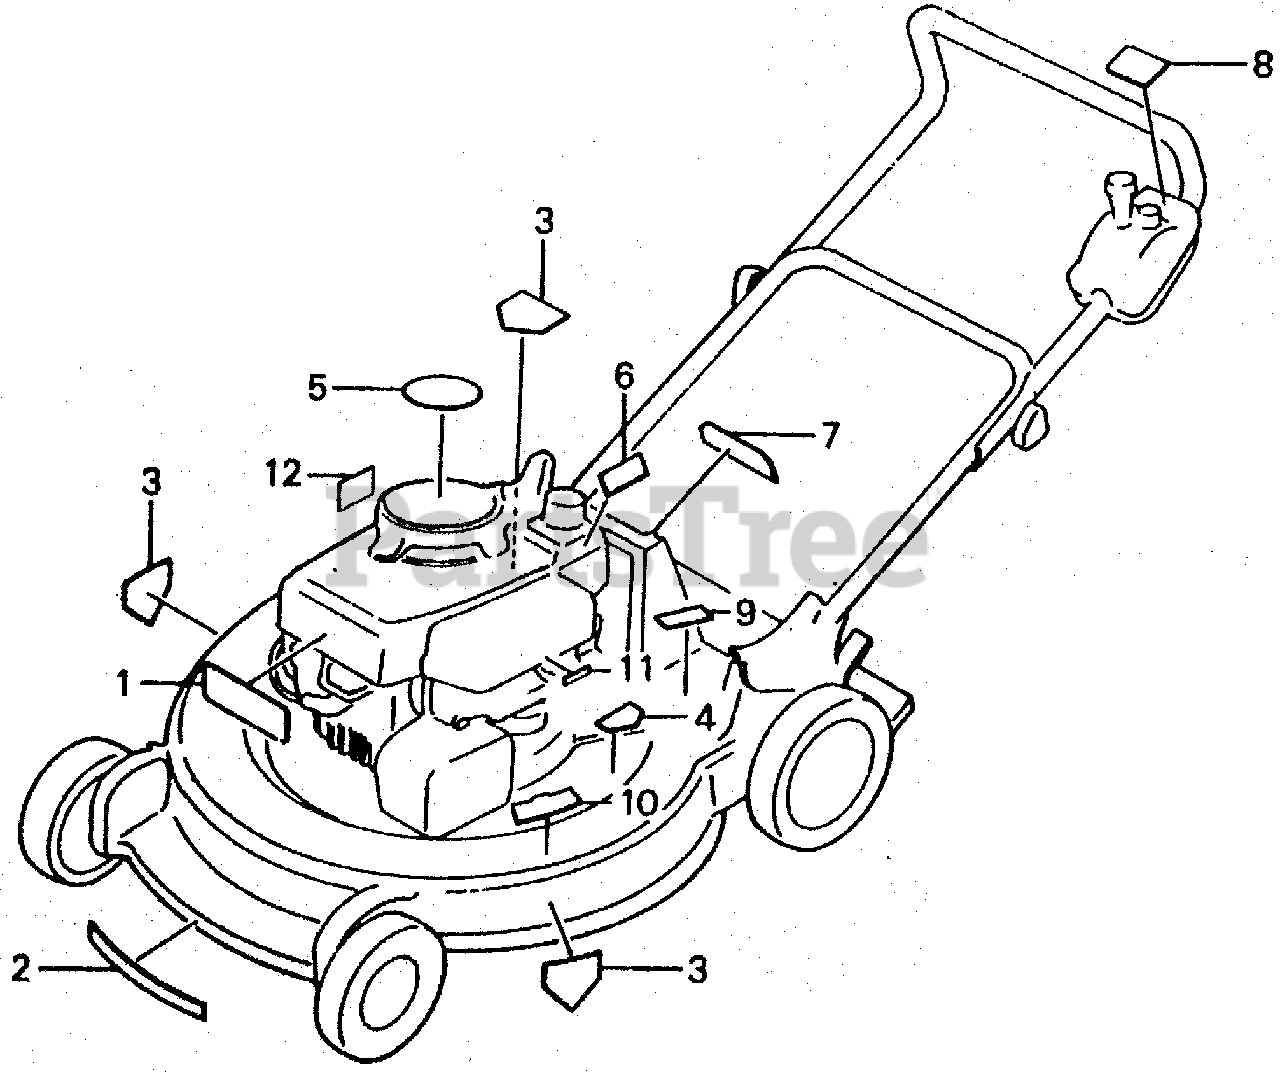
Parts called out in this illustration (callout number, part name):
1	MARK, TOP COVER
2	LABEL A, HOUSING CAUTION
3	LABEL B, HOUSING CAUTION (ENGLISH)
4	LABEL, STEP POSITION (ENGLISH) (NOT AVAILABLE)
5	CAUTION, OPERATOR (ENGLISH)
6	LABEL, FUEL CAUTION (ENGLISH)
7	LABEL, DISCHARGE GUARD CAUTION (ENGLISH) (NOT AVAILABLE)
8	LABEL, CONTROL COVER CAUTION (ENGLISH) (NOT AVAILABLE)
9	CAUTION, BELT COVER (ENGLISH)
10	LABEL, PLUG CAUTION (ENGLISH)
11	MARK, AIR CLEANER CAUTION
12	MARK, OIL CAUTION
